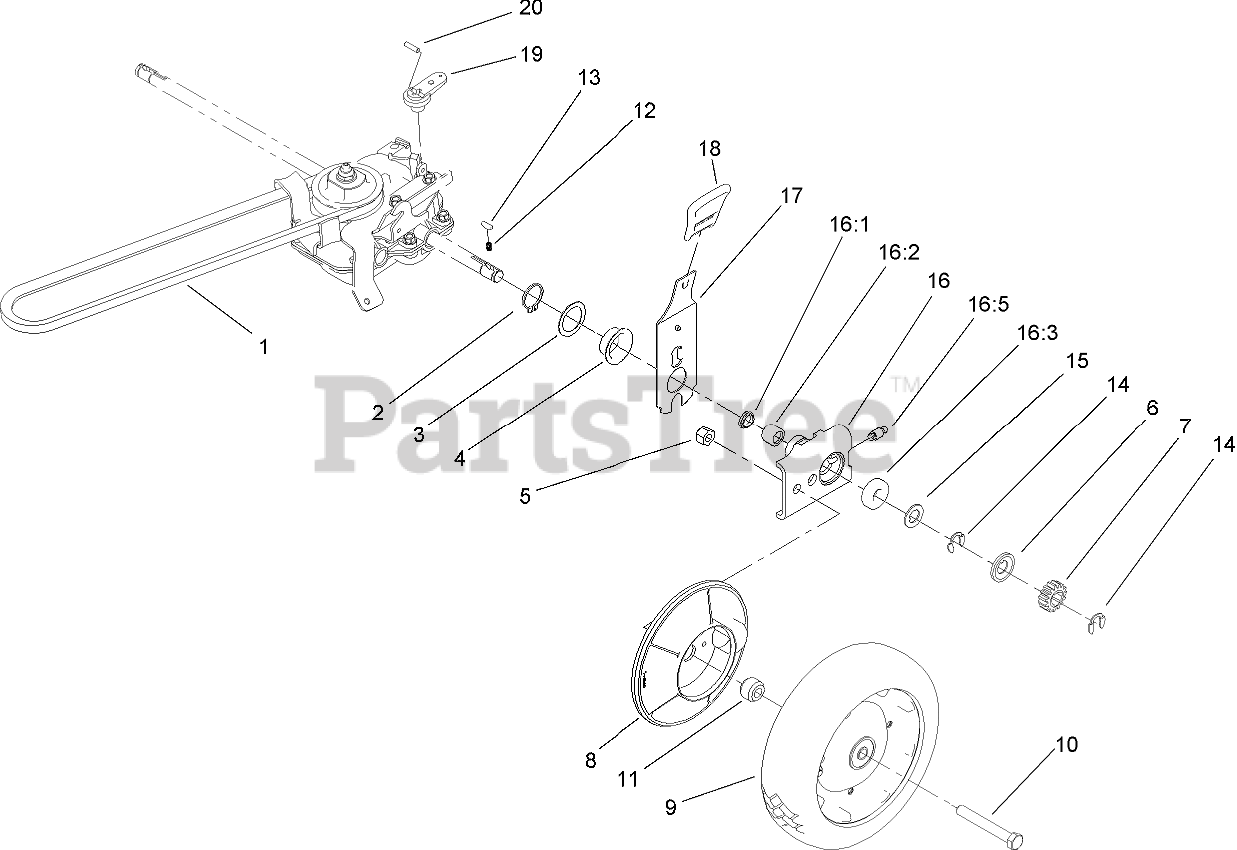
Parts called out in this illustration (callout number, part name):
1	V-BELT
2	RING-RETAINING
3	WASHER
4	CAP-END
5	NUT-LOCK, CONE
6	WASHER-THRUST, OUTER
7	GEAR-PINION
8	COVER-WHEEL
9	Wheel And Tire ASM
10	SCREW-HH
11	SPACER-COVER, WHEEL
12	SPRING-COMPRESSION
14	RING-RETAINING
15	WASHER-THRUST, OUTER
16	PIVOT ARM ASM
16:1	SEAL-OIL
16:2	BEARING-ROLLER
16:3	BEARING-WHEEL
17	REAR SPRING ARM ASM
18	KNOB-HOC
19	LEVER-SHIFT
20	PIN-COIL
